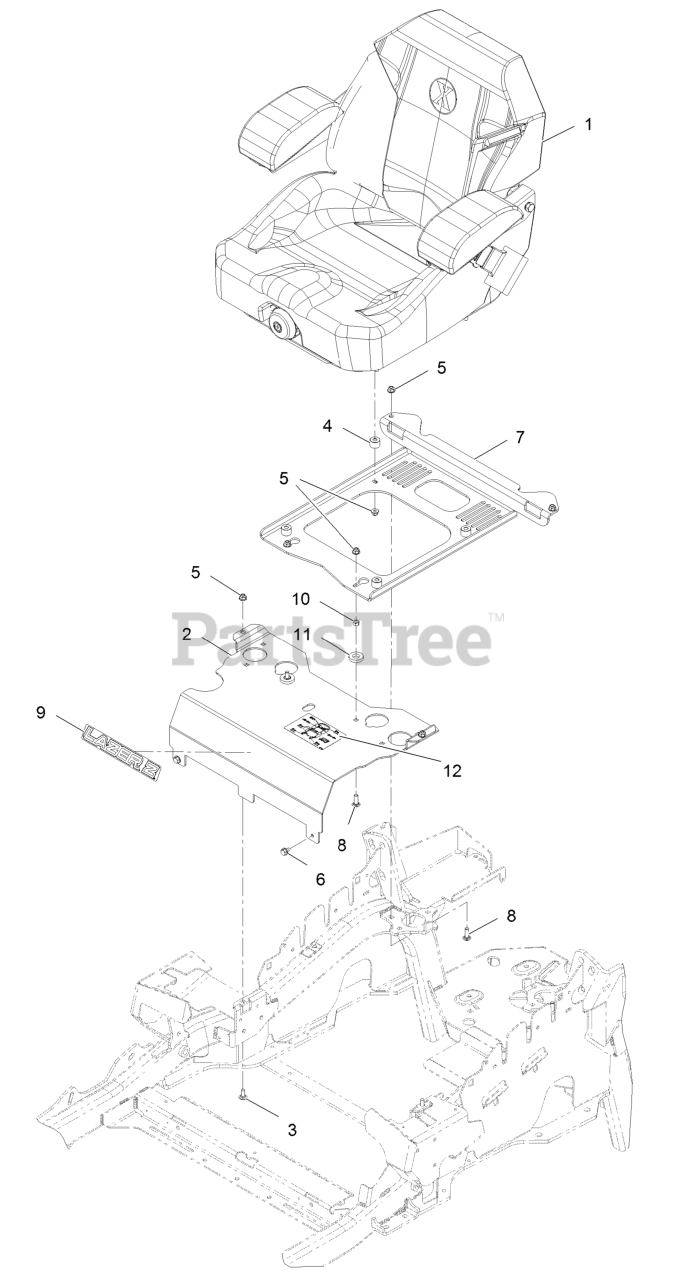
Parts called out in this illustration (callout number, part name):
1	KIT-SUSPENSION SEAT
2	Panel-Front, Seat Mount
3	SCREW-CARR
5	NUT-HF, NI
7	PLATE-SUPPORT, SEAT
8	SCREW-CARR
9	DECAL, LAZER MODEL
10	NUT-HEX
12	DECAL-SERVICE AID
